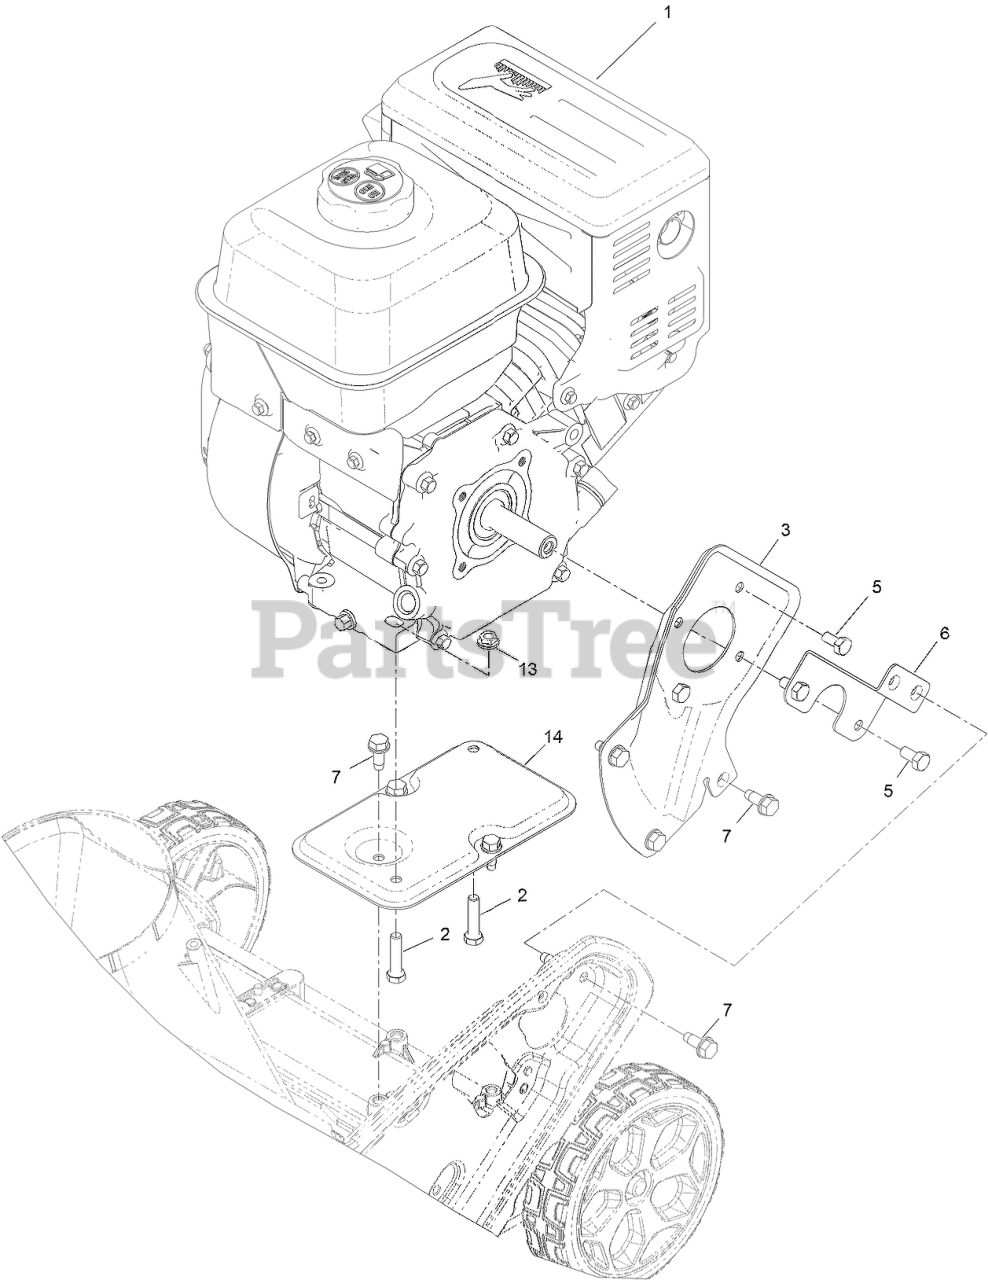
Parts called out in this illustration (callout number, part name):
1	ENGINE - G210FDS-4
2	SCREW-HH
3	PLATE-ENGINE, PTO
5	BOLT
6	SUPPORT-ENGINE, SIDE
7	SCREW-THD ROLL, HWH
13	NUT-HF
14	SUPPORT-ENGINE
